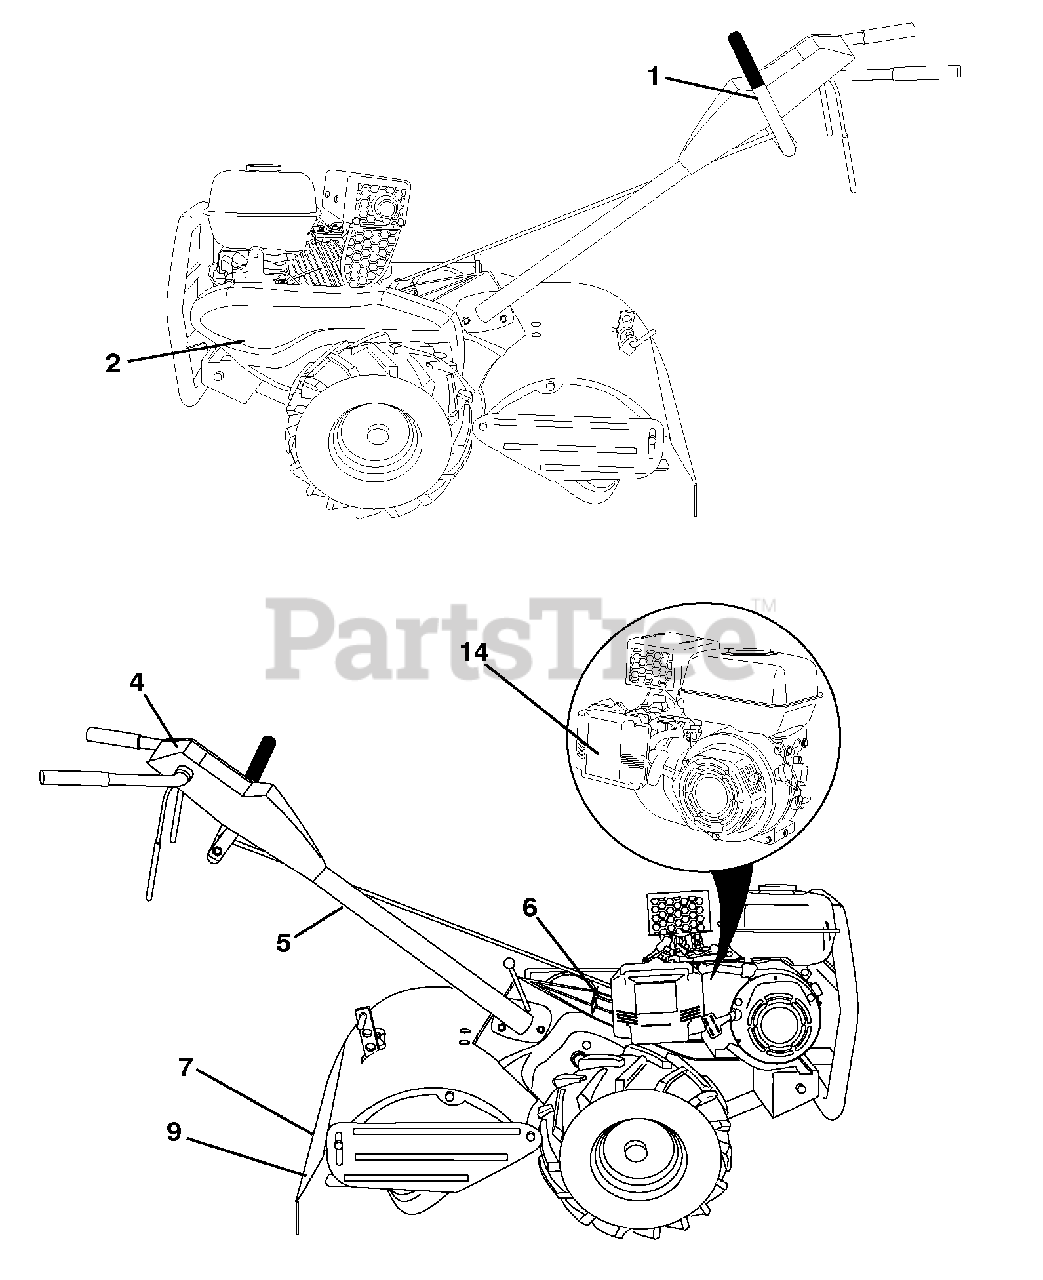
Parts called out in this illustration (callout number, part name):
1	Decal, CNTRL PNL
2	Decal, Decal, Blt Grd
4	Decal, Control, Panel Oper.
5	Decal, Hand Placement
6	Decal, Shift Indicator
7	Decal, Caution
9	Decal, Warning, Rotating Tines
14	Decal, Air Cleaner
14	Manual, Operator's, English/French
14	Manual, Repair Parts, English/French
